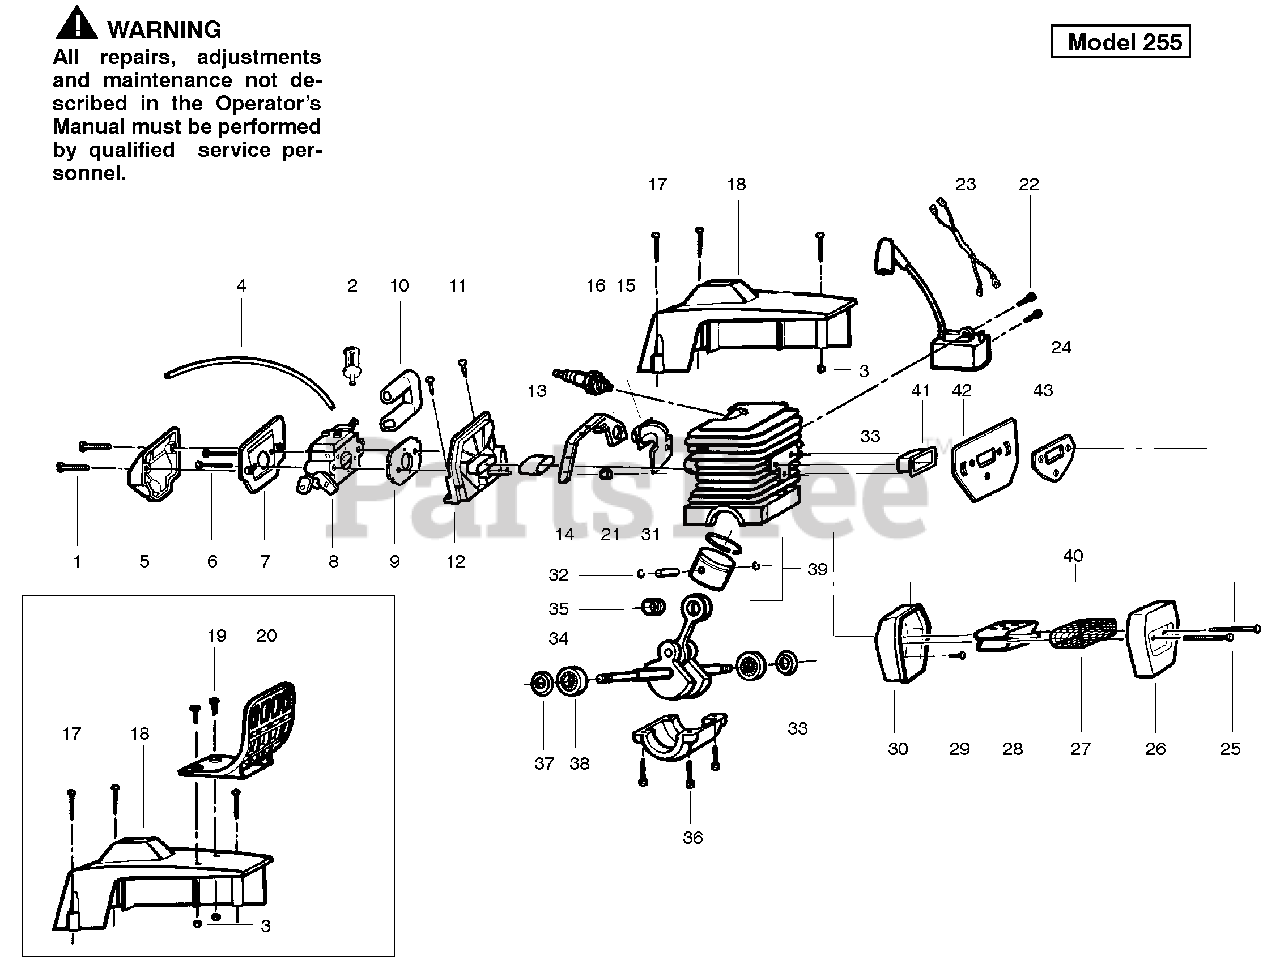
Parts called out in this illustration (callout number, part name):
2	Fuel Pick-up
4	Fuel Line
5	Air Filter (Top)
7	Air Filter (Bottom)
8	Carburetor Type 1,2,3,4
8	Carburetor Type 5
9	Carb. Gasket
10	Carb. Grommet Type 1,2,3,4
10	Carb. Grommet Type 5
11	Screw
12	Carb. Adaptor
13	Intake Sleeve
14	Turbo Clean Seal
15	Turbo Air Cleaner Ass'y.
16	Spark Plug (CJ-7Y)
18	Cylinder Shield Kit
20	Handguard
21	Impulse Seal
23	Switch Wire Ass'y.
24	Ignition Module
25	Muffler Bolt 5 mm
25	Muffler Bolt 6 mm
26	Muffler Cover
27	Spark Screen
28	Diffuser
30	Muffler Body
31	Piston Ring
32	Piston Pin Retainer
33	Cylinder Kit
34	C'shaft & Rod Ass'y.
35	Piston Pin Bearing
37	C'shaft Seal
38	C'shaft Bearing
39	Piston Kit
40	Muffler Kit
41	Heat Insulator
42	Muffler Plate
43	Muffler Gasket
